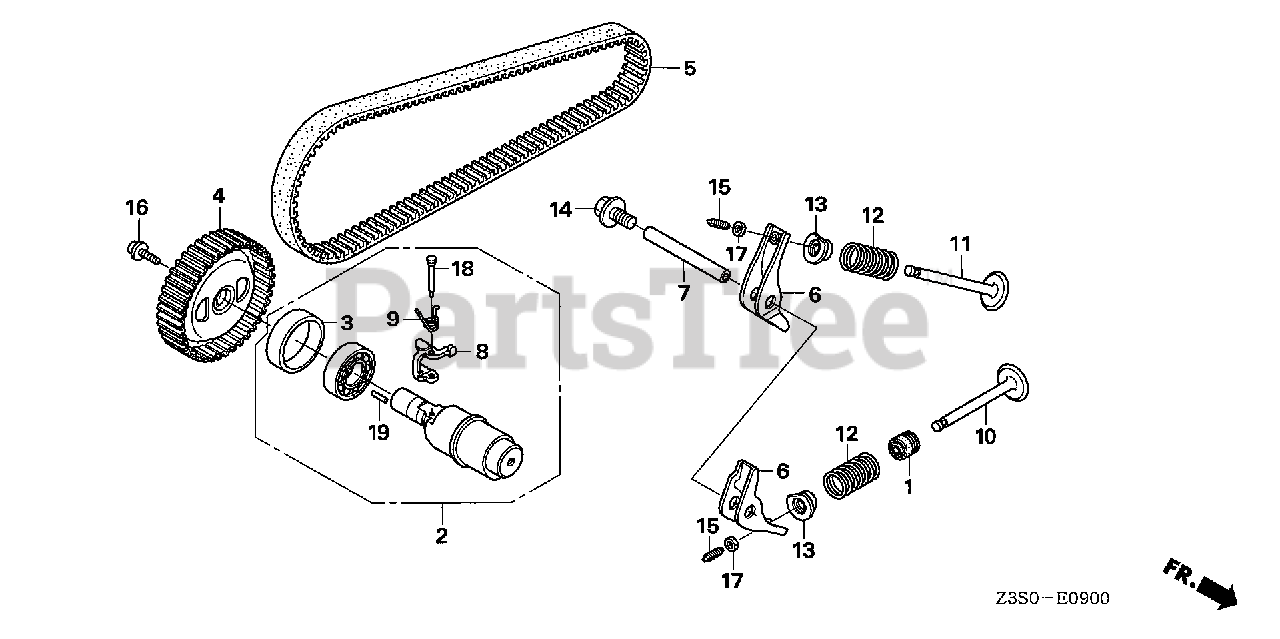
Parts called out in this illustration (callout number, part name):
1	SEAL, VALVE STEM (ARAI)
2	CAMSHAFT ASSY.
3	BUSH, CAMSHAFT BEARING
4	PULLEY, CAMSHAFT
5	BELT, TIMING
6	ARM, VALVE ROCKER
7	SHAFT, ROCKER ARM
8	WEIGHT, DECOMPRESSION
9	SPRING, WEIGHT RETURN
10	VALVE, IN.
11	VALVE, EX.
12	SPRING, VALVE
13	RETAINER, IN. VALVE SPRING
13	RETAINER, VALVE SPRING (EXHAUST SIDE)
14	BOLT, FLANGE (12X18)
15	SCREW, TAPPET ADJUSTING
16	BOLT, FLANGE SOCKET (6X16)
17	NUT, TAPPET ADJ.
18	PIN, WEIGHT CENTER
19	ROLLER (2X13.8)
